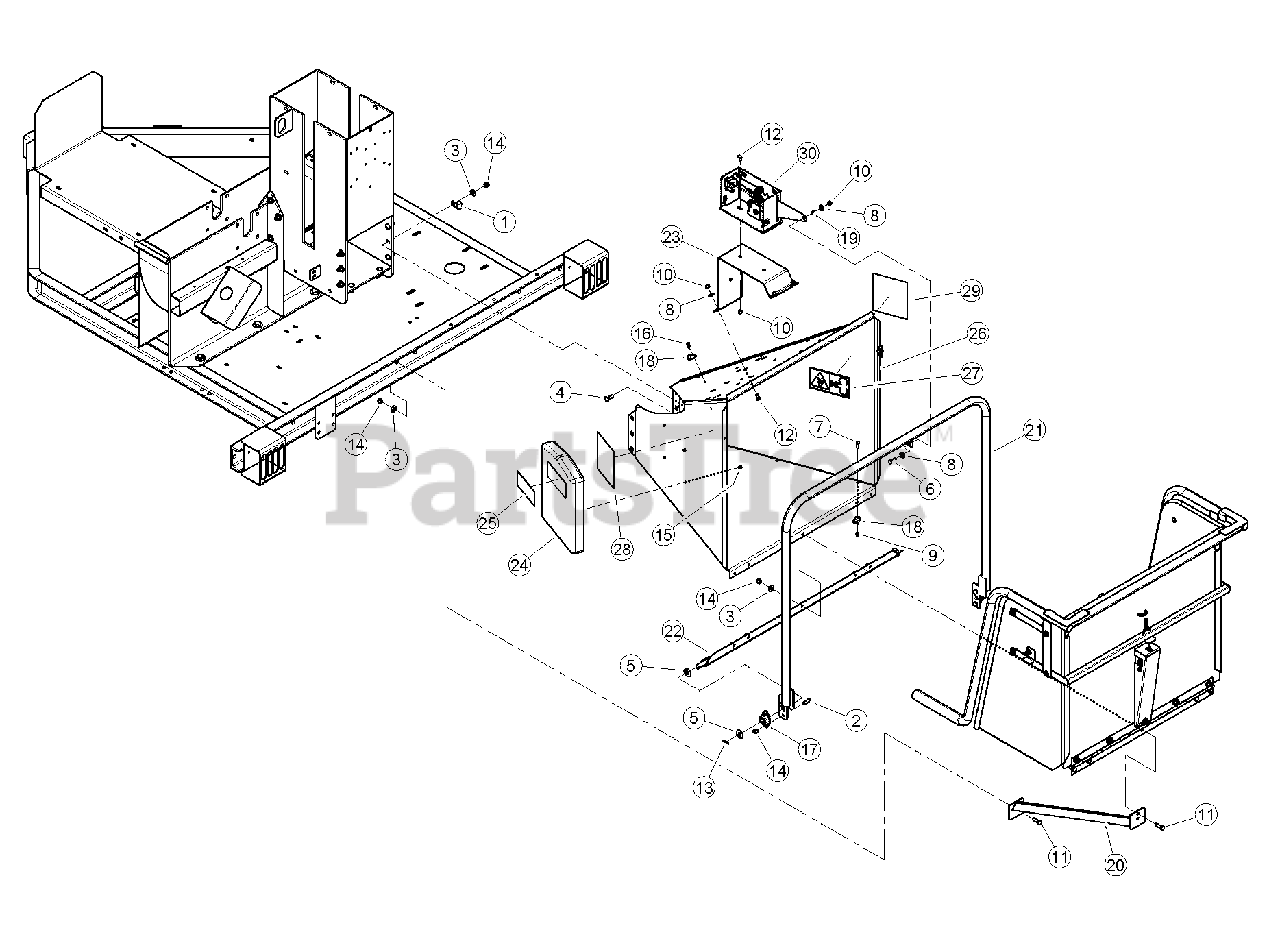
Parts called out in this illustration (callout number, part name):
1	CLAMP, 9/16" COATED
2	BOLT, 3/8 X 1 HEX HD GR5 ZP
3	WASHER, 3/8 FLAT ZP
4	BOLT, 3/8 X 1-1/2 CRG GR5 NC ZP
5	WASHER, 5/8 SAE FLAT ZP
6	BOLT, 5/16 X 1 HHCS GR5 NC ZP
7	BOLT, 1/4 X 1 CRG GR5 NC ZP
8	WASHER, 5/16 FLAT ZP
9	NUT, 1/4 NE NYLOCK ZP
10	NUT, 5/16 NE NYLOCK ZP
11	BOLT, 3/8 X 1-1/4 HEX HD GR5 ZP
12	BOLT, 5/16 X 3/4 CRG GR5 NC ZP
13	PIN, 1/8 X 1.00 ZP COTTER
14	NUT, 3/8 NE NYLOCK ZP
15	RIVET, AL BLIND 1/4 X 1/2 DOME HEAD
16	RIVET, AL BLIND 1/4 X 3/4 DOME HEAD
17	BEARING, SIDE FLANGE MOUNT, 5/8
18	CLAMP, CABLE MOUNT
19	SPACER, IDLER PIVOT
20	WELDMENT, CHUTE SUPPORT
21	WELDMENT, CONTROL ARM
22	WELDMENT, CONTROL PIVOT
23	MOUNT, SWITCH BOX
24	ASSEMBLY, MANUAL CONTAINER SERVICE PART
25	DECAL, MUTILINGUAL MANUAL
26	ASSEMBLY, BIG CHIPPER CHUTE SERVICE PART
27	DECAL, BLADE DANGER ISO
28	DECAL, FEED POSITION
29	DECAL, FEED POSITION
30	ASSEMBLY, SWITCH BOX
